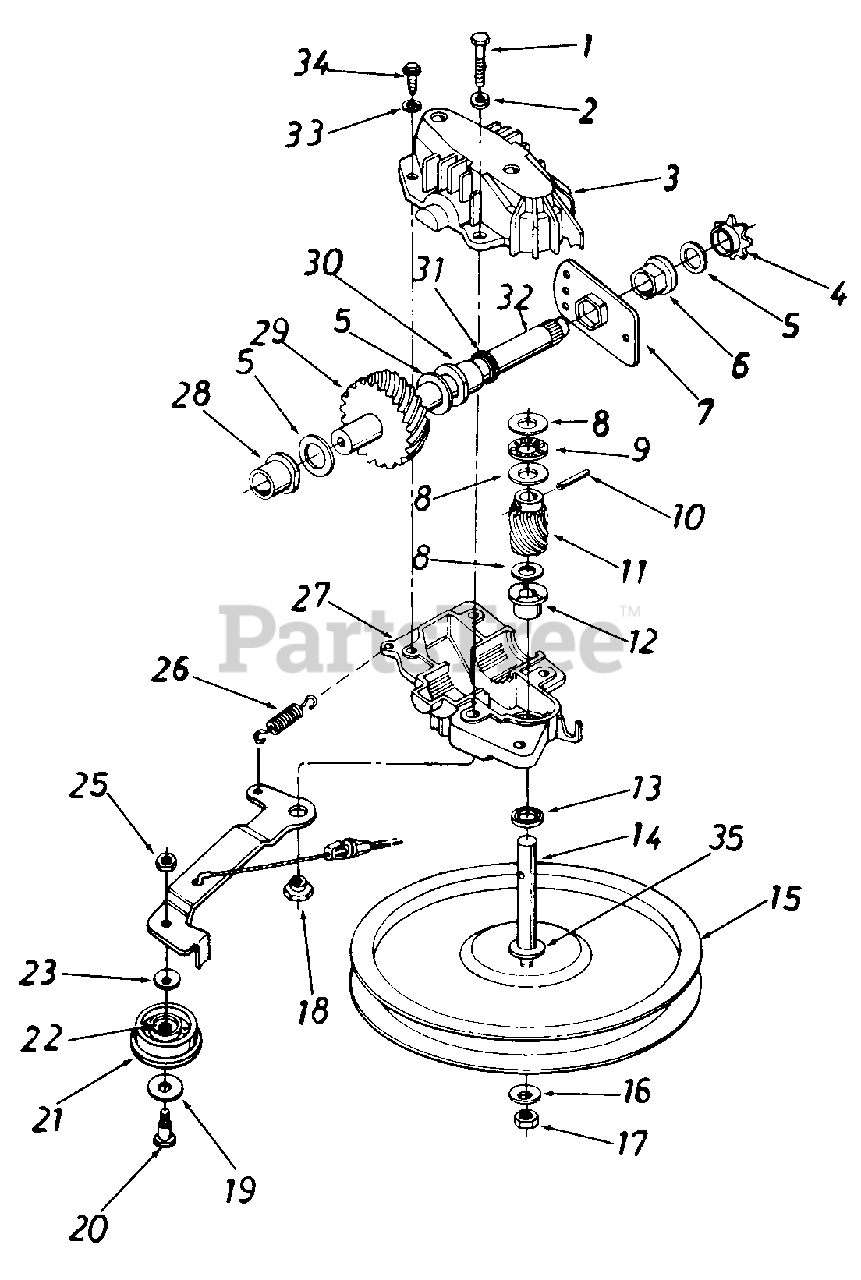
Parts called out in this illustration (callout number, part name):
1	Hex Bolt 1/4-20 x 1.25" Lg.
2	L-Wash. 1/4" I.D.
3	Upper Hsg. Half 0287040003
4	#48 Sprocket 7 Tooth x 1/2 Pitch
5	Fl-Wash. 5/8" I.D. x .030
6	Hex Flange Brg. .631" I.D.
7	Hex Bearing Cup
8	Thrust Wash. .382" I.D. x .70" O.D.
9	Thrust Bearing .375" I.D. x .812" O.D.
10	Spring Pin Spir. 1/8" x .62" Heavy
11	11 Tooth Helical Gear
12	Flange Bearing
13	Oil Seal
14	Pulley-Transmission Shaft
15	Fl-Pulley 5.06" O.D.
16	Bell-Wash. .265" I.D. x 75"
17	Hex L-Nut 1/4-28 Thd.
18	Shld. Spacer .375" Dia. x .170
19	Fl-Wash. .390" I.D. x 1.0"
20	Shld. Bolt .375" Dia. x .40"
21	Fl-Idler Plastic 1.50" Dia.
22	Needle Brg. .375" x .31
23	Bell-Wash. .265" I.D. x 75"
24	Idler Brk't. Ass'y.
25	Hex Patch L-Nut 1/4-28 Thd.
26	Extension Spring 1.12" Lg.
27	Lower Hsg. Half
28	Flange Bearing .566 Dia.
29	33 Tooth Helical Gear
30	Flange Bearing .629 Dia.
31	Oil Seal .625 Dia.
32	Gear Sprocket Shaft
33	L-Wash. #10 I.D.
34	Hex B-Tap Scr. #10 x .62"
35	Hex Washer .26" x .88"
